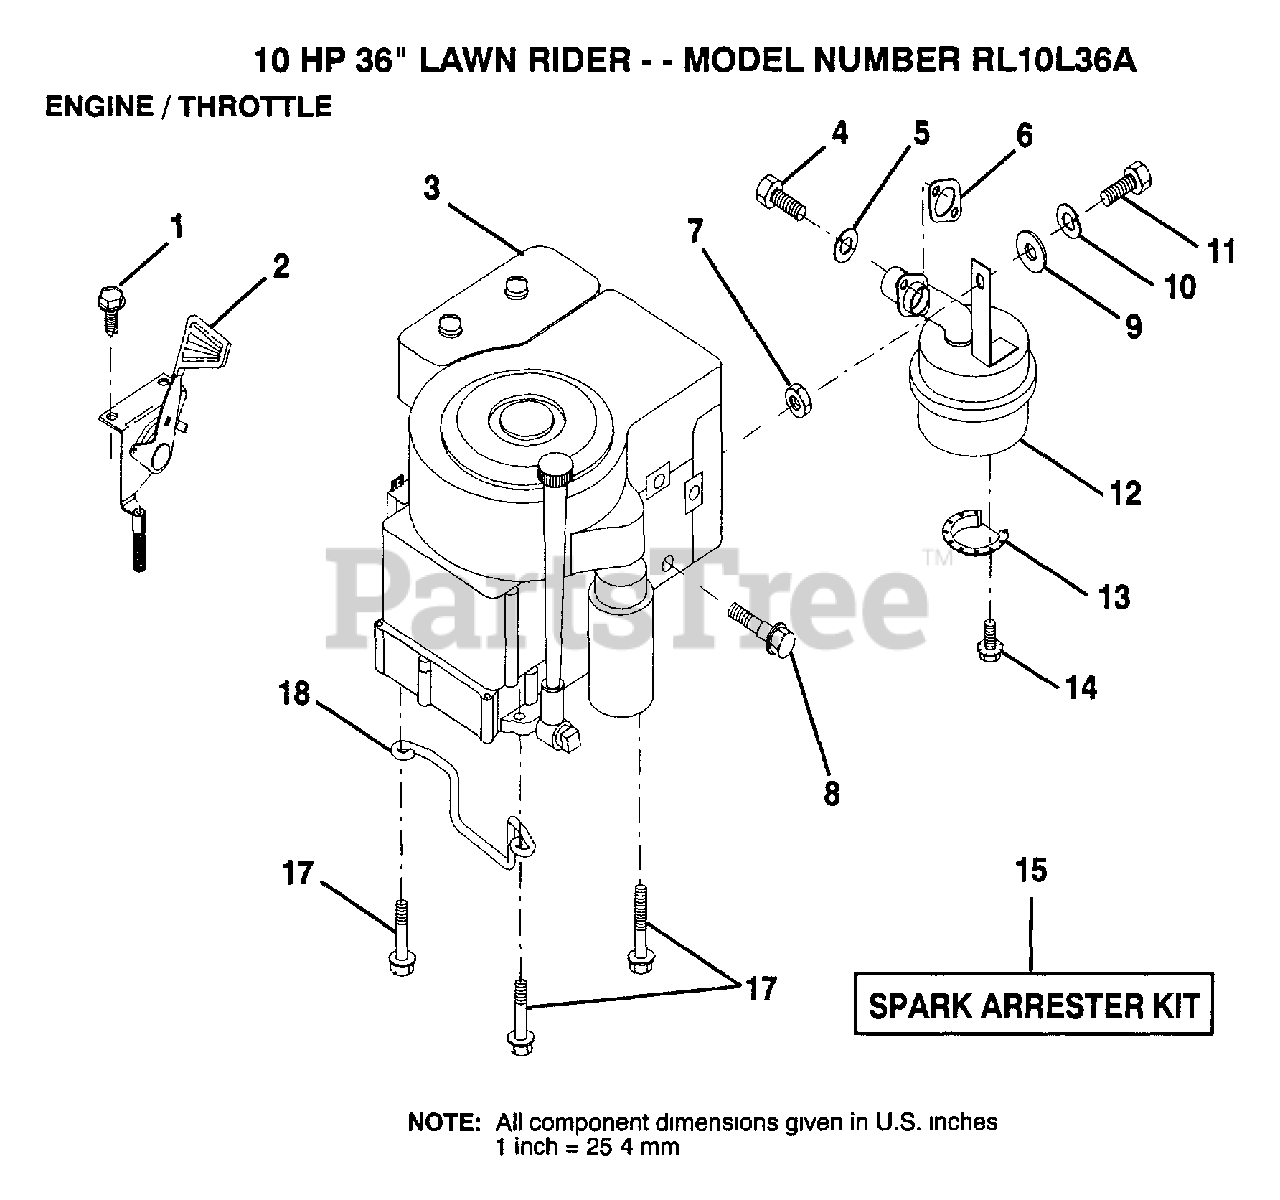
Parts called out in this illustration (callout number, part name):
1	SCREW
2	THROTTLE CONTROL
4	SCREW
5	LOCKWASHER
7	NUT.HEX.5/16-18
8	BOLT T
10	LOCKWASHER
12	MUFFLER
13	DEFLECTOR.222573
17	SCREW LT
18	"KEEPER,DR BELT GR"
